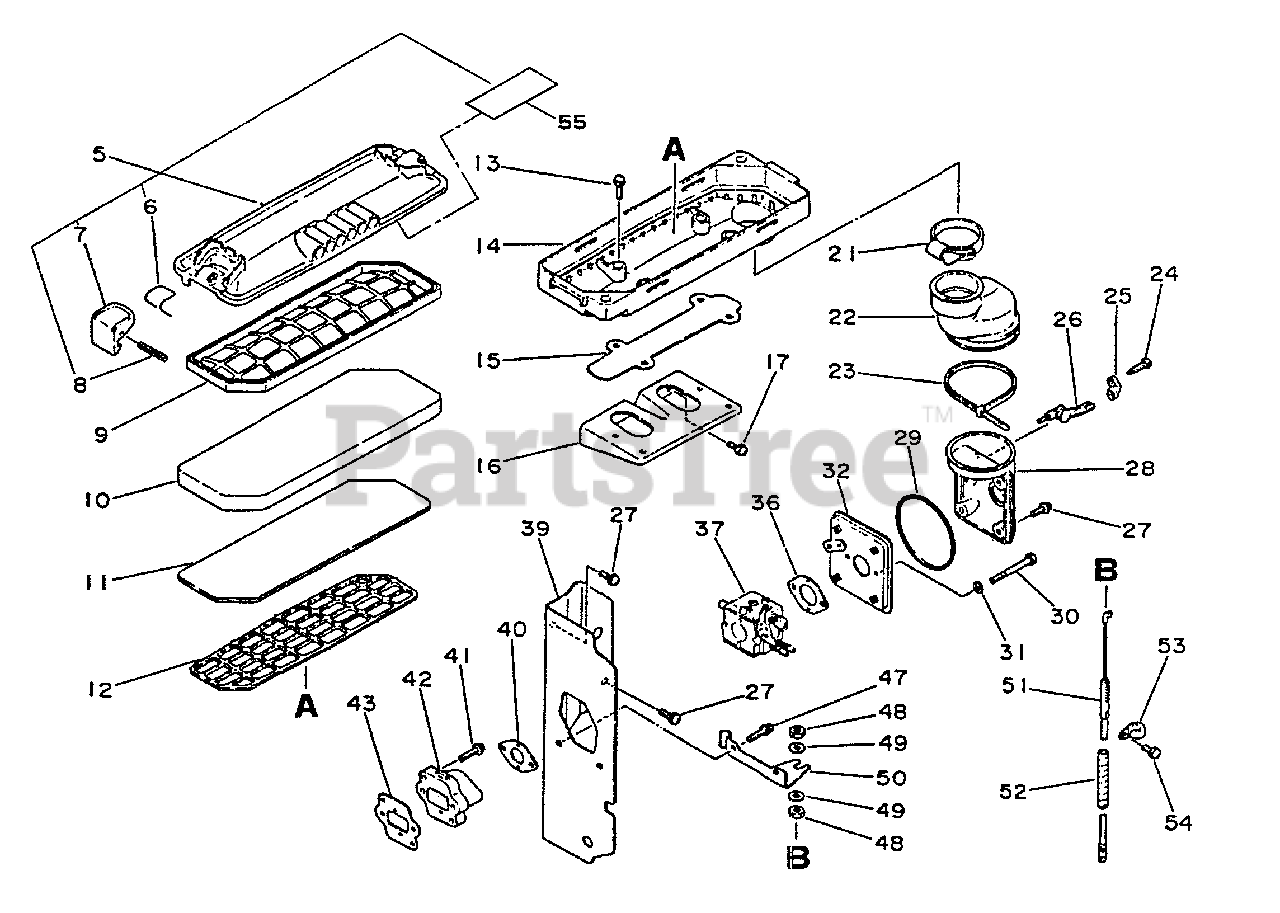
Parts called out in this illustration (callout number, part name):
5	COVER, AIR FILTER
6	HOOK, SPRING
7	HOOK
8	PIN, SPRING 3×25
9	GRID, AIR FILTER
10	FILTER, AIR
11	FILTER, AIR
12	RETAINER, AIR FILTER
13	SCREW 4×12
14	COVER, AIR FILTER
15	PLATE
16	BRACKET, AIR FILTER
17	SCREW 5×14
21	BAND
22	ADAPTER, INTAKE
24	SCREW 4×16
26	ROD, CHOKE
27	SCREW 4×10
29	GASKET
30	BOLT
31	WASHER, FLAT 5.5×10×0.8
32	BRACKET, CARBURETOR
36	GASKET, INTAKE
37	CARBURETOR
39	INSULATOR
40	GASKET, INTAKE
41	SCREW - 5×25
42	INSULATOR, INTAKE
43	GASKET, INTAKE
47	SCREW 4×12
49	WASHER 6.5×11.5×0.8
51	CABLE, THROTTLE
54	SCREW - 6×10
